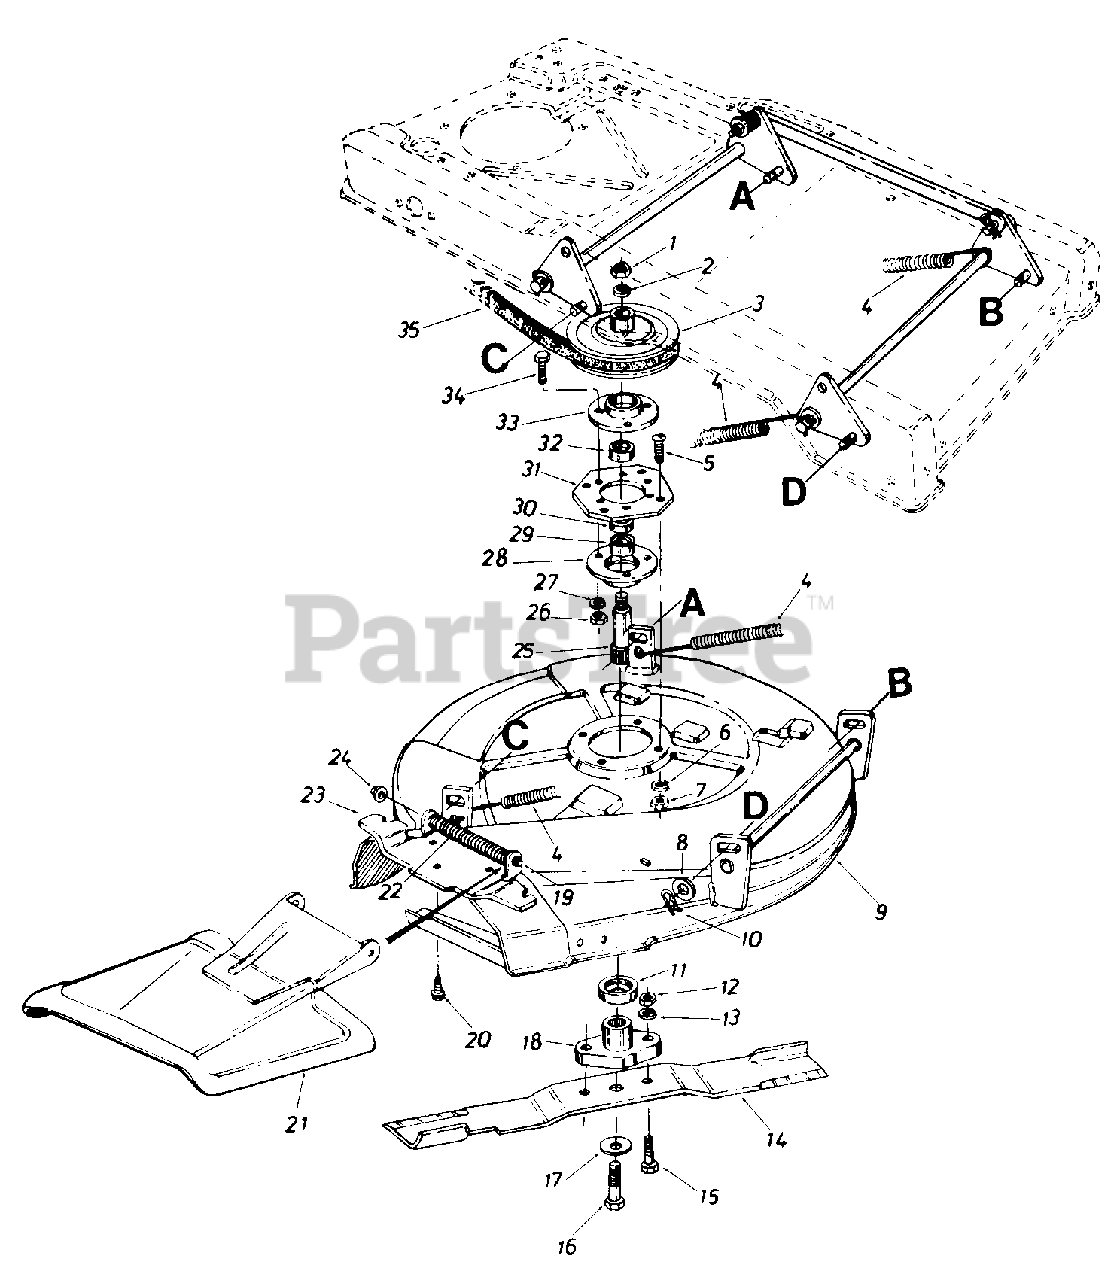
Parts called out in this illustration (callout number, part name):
1	Hex Jam Nut 5/16-18 Thd.
2	Bell-Wash. .630" I.D. x 1.25 O.D.
3	518" "V"-Pulley .75" I.D. x 9.5"
4	Extension Spring .56" O.D. x 10.5
5	Hex Bolt 5/16-18 x .75" Lg.*
6	L-Wash. 5/16" I.D.*
7	Hex Nut 5/16-18 Thd.*
8	Fl-Wash. .510" I.D. x 1.01' O.D.
9	26" Deck Ass'y
10	Inter. Cotter Pin 1/2" Dia.
11	Bearing Shield
12	Hex Nut 5/16-24 Thd.*
13	L-Wash. 5/16" I.D.*
14	Blade 26"
15	Hex Bolt Special 5/16-24 x 1.0" Lg.
16	Hex Bolt 3/8-24 x 1.00" Lg.
17	Bell-Wash. .391" I.D. x 1.38" O.D.
18	Blade Adapter
19	Hinge Pin
20	Hex Wash. Hd. TT-Scr. 1/4-20
21	Chute Cover Ass'y.
22	Torsion Spring
23	Adapter Plate
24	Cap Speed Nut 1/4" Rod
25	Blade Spindle 4.42" Lg.
26	Hex Nut 5/16-18 Thd.
27	L-Wash. 5/16" I.D.
28	Bearing Housing 1.85
29	Ball Brg. .787" I.D. x 1.85" O.D.
30	Spacer 1.0" O.D. x .790" I.D. x.350" Lg.
31	Spindle Mounting Plate
32	Ball Brg. .787" I.D. x 1.85" O.D.
33	Open Brg. Housing 1.85
34	Hex Bolt 5/16-18 x .75" Lg.
35	"V"-Belt
